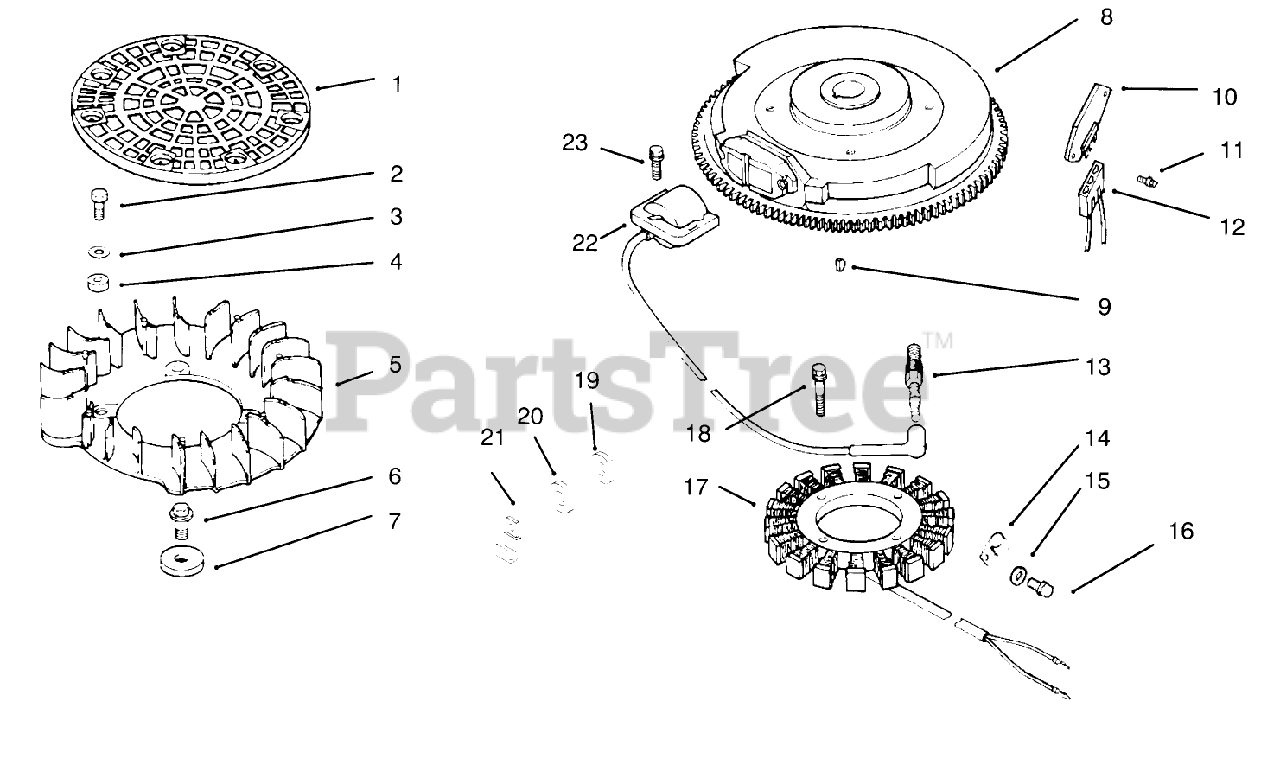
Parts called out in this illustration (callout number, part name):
1	Screen-Grass (Only On: 72103, 72083)
3	Washer
4	Spacer-Fan (Only On: 72103)
5	Fan (Only On: 72103, 72083)
7	Spacer-Fan
8	Flywheel ASM (Only On: 72103, 72083)
10	Rectifier-Regulator
12	Connector
13	Spark Plug
16	Screw
17	Stator-15 amp
19	Washer
20	Washer
22	Module-Ignition
